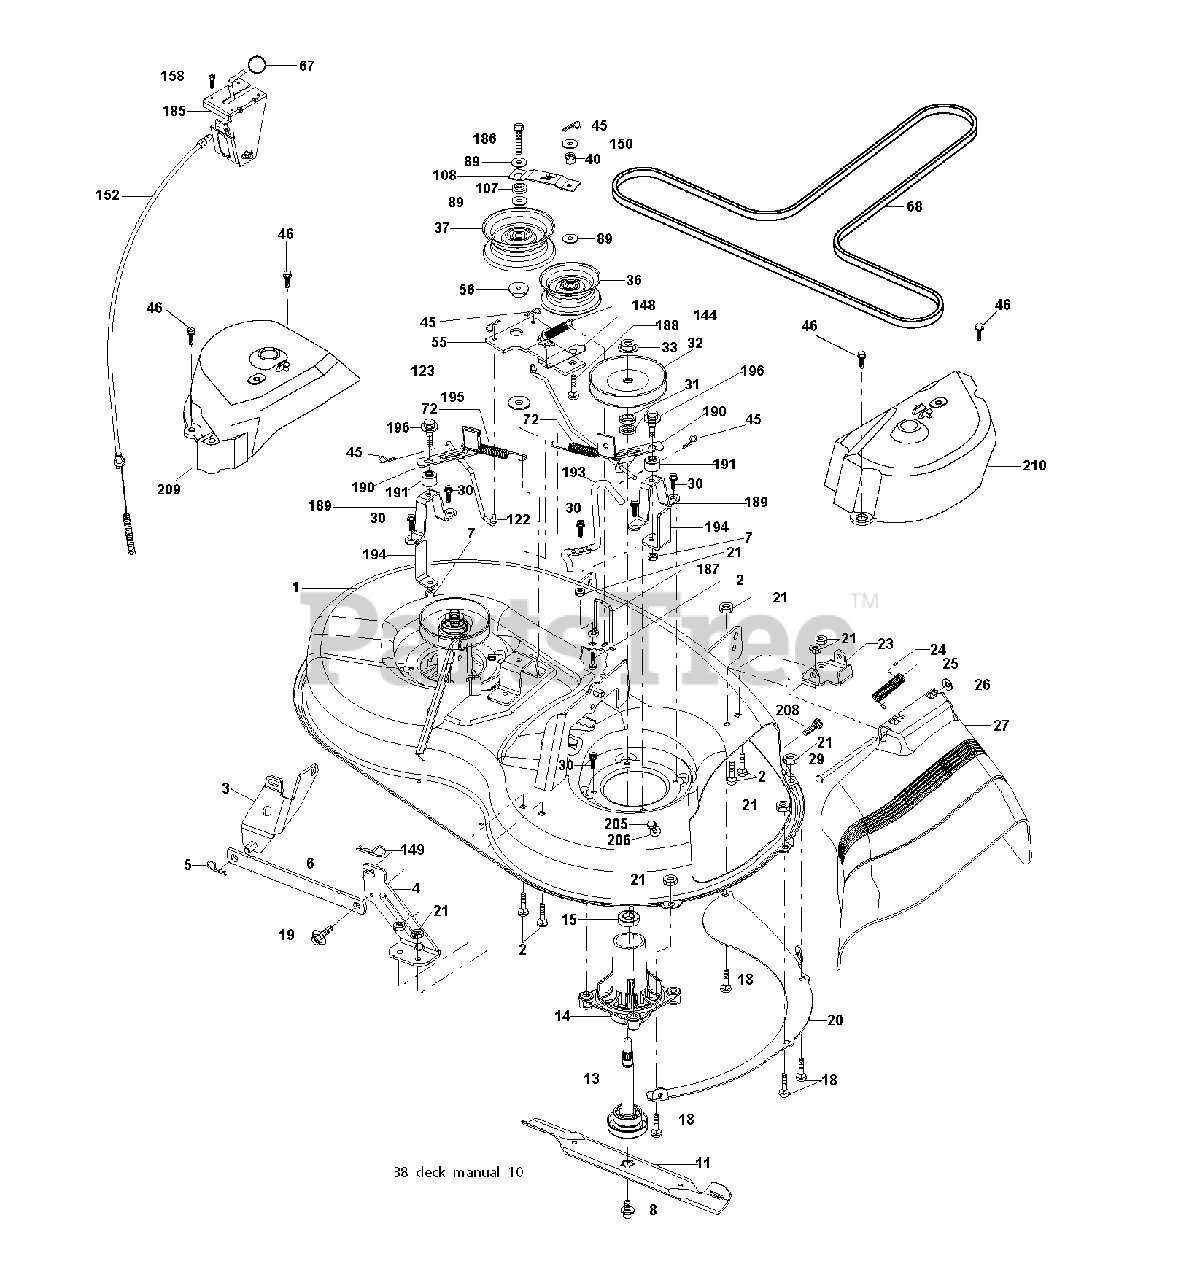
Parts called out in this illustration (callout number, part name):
1	DECK.WELDMENT.38"2005
2	BOLT
3	BRKT ASM SWAY BAR
4	BRACKET DECK SWAY BAR 38"/42"
5	RETAINER-SPRNG RB
6	BAR SWAY DECK
7	NUT.71038.31-18.HEX.NYLOCK
8	BOLT.WASHER.ASM.7/16-2
11	BLADE 38" PREMIUM
13	SHAFT.ASM.MDRL.N/GREASE.38
14	HOUSING MANDREL
18	BOLT
19	BOLT SHD 5/16-18
20	BAFFLE VORTEX
21	LOCKNUT
23	BRKT.DEFLECTOR.38"2005+
24	CAP-SLEEVE LT
25	SPRING.TORSION.DEFLECT
26	NUT PUSH M
29	ROD.HINGE
30	SCREW, WASHER HEAD
31	WASHER.SPACER.MANDREL
32	PULLEY MANDREL
33	NUT.FLANGE.LOCK.TOP
36	FLAT IDLER PULLEY
37	PULLEY.IDLER.FLAT.UNPLATED
40	LOCKNUT
45	RETAINER M
46	SCREW.1/4-20X5/8
55	IDLER ARM
56	SPACER.RETAINER.MOWER
67	KNOB T (3/8 HOLE)
68	V-BELT.MOWER.38"2005+
72	SPRING.BRAKE.RETURN.38"
89	WASHER
107	SPACER.IDLER.ARM
108	STIFFENER.IDLER.ARM
122	ROD, BRAKE LH LINK
123	LINK.BRAKE.38"RIGHT
144	KEEPER BELT
148	IDLER RETURN SPRING
149	SPRING.RETAINER.YELLOW.ZINC
150	WASHER LT
152	CABLE.CLUTCH.38".SERVICE
158	SCREW
185	HEAD ASM. CABLE CLUTCH
186	SCREW.HXWSH.3/8
187	KEEPER BELT
188	BOLT, CARRIAGE IDLER
189	STAND, BRAKE
190	ARM, BRAKE
191	SPACER, BRAKE
193	KEEPER BELT RH MANDREL
194	GUARD BRAKE
195	WASHER 12/32X2X10GA
196	BOLT/WASHER ASM 5/16-18
205	SCREW
208	SCREW 3/8-16X1/2
